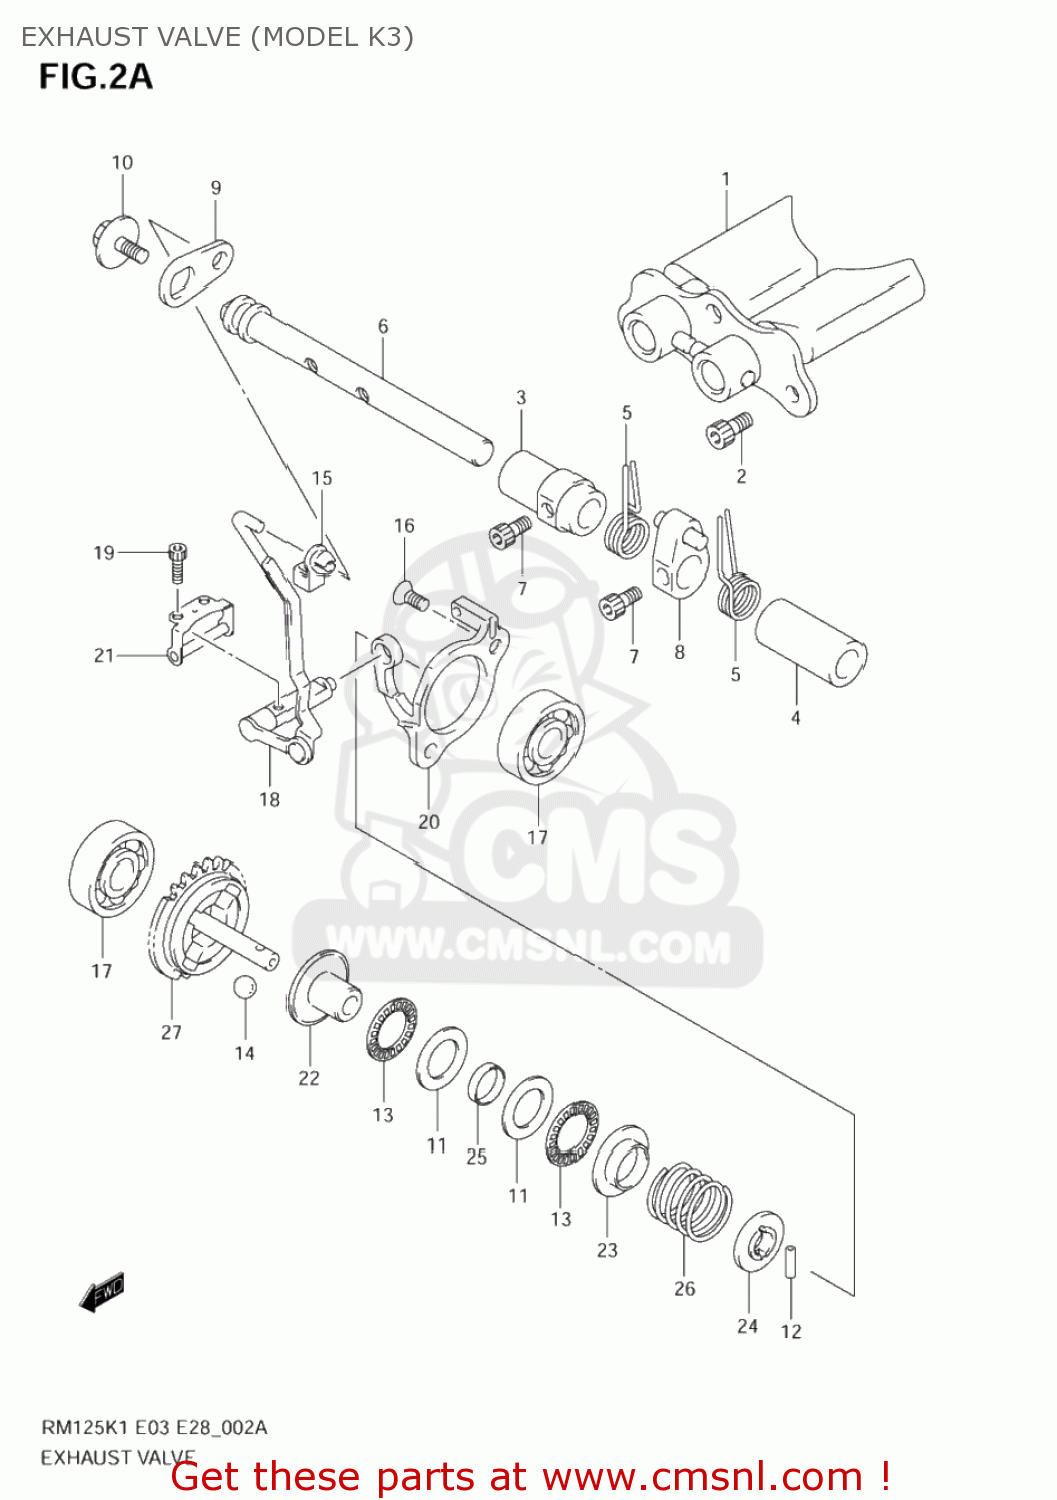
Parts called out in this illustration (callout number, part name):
1	VALVE SET, EXHAUST
2	BOLT
3	SPACER,EXHAUST VALVE SHAFT
4	SPACER (8.2X12.5X23.5)
5	SPRING,EXHAUST VALVE SHAFT ARM
6	SHAFT,EXHAUST
7	BOLT(4X8)
8	ARM,EXHAUST VALVE SHAFT
9	LEVER,EXHAUST VALVE NO.1
10	BOLT(5X12)
11	SHIM(15X28X1)
12	ROLLER(3X12.5)
13	BEARING(15X28X2)
14	BALL
15	BUSH,EXHAUST VALVE ROD NO.1
16	SCREW(5X10)
17	BEARING(8X22X7)
18	ACTUATOR,EXHAUST VALVE
19	BOLT(4X8)
20	BASE,ACTUATOR
21	ARM,ACTUATOR
22	GOVERNOR,DRIVEN
23	STOPPER,GOVERNOR SPRING NO.1
24	STOPPER,GOVERNOR SPRING NO.2
25	SPACER,GOVERNOR
26	SPRING,GOVERNOR
27	GOVERNOR SET,EXHAUST
